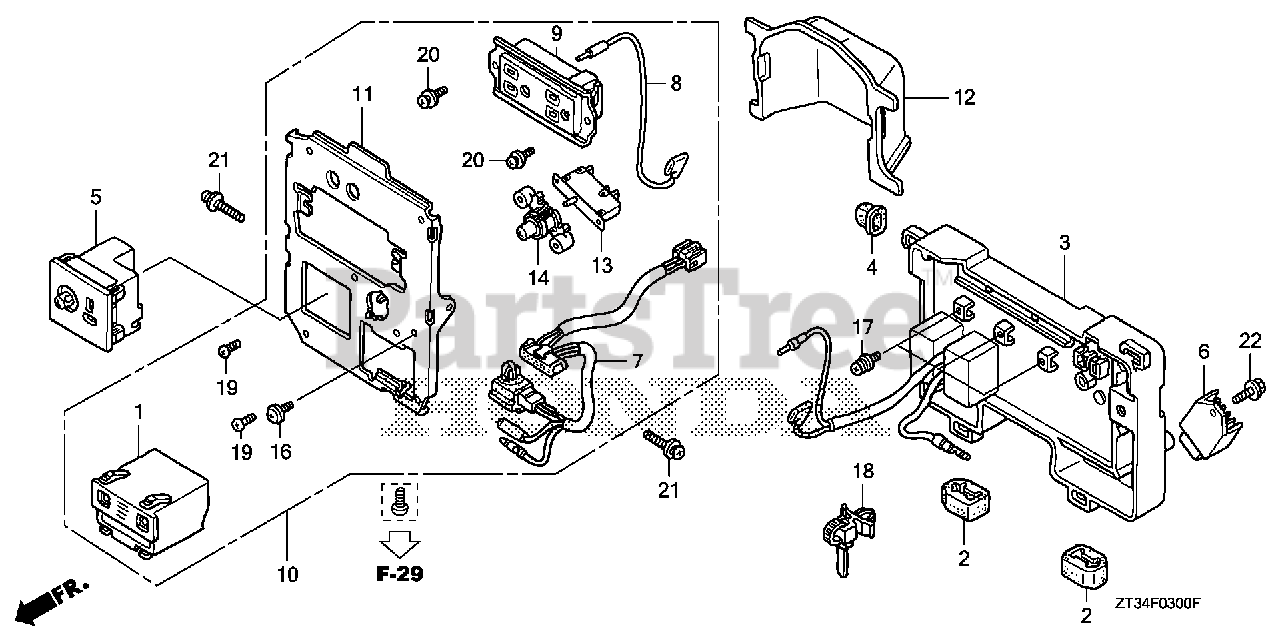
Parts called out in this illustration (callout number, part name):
1	SPARK UNIT
2	RUBBER A, INVERTER
3	CYCLOCONVERTER UNIT
4	RUBBER B, INVERTER
5	RECEPTACLE, D.C. (6.3A)
6	RECTIFIER ASSY.
7	WIRE HARNESS ASSY., CONTROL
8	WIRE, TERMINAL
9	RECEPTACLE ASSY. (15A/125V)
10	PANEL ASSY., CONTROL
11	PANEL, CONTROL
12	COVER, CONTROL PANEL
13	PROTECTOR, CIRCUIT (5A)
14	LENS ASSY., PROTECTOR
16	SCREW, PAN (5X12)
17	SCREW-WASHER (4X6)
18	BAND (100MM) (BLACK)
19	SCREW, PAN (3X12) (NOT AVAILABLE)
20	SCREW-WASHER (4X6)
21	SCREW-WASHER (5X20)
22	BOLT, FLANGE (6X12)
